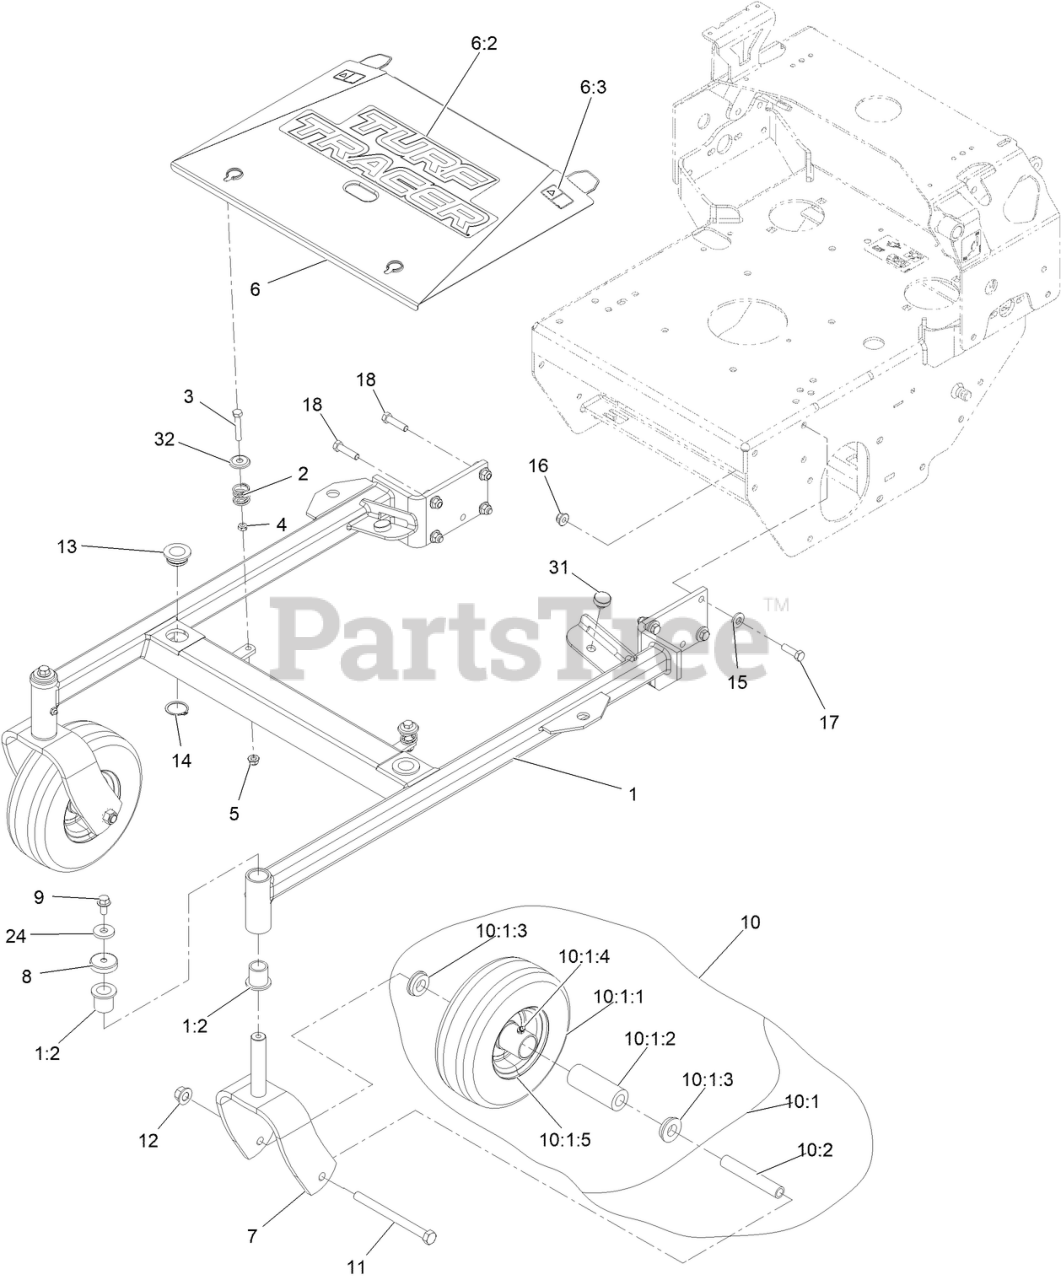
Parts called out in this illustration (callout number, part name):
1	ASM-36" Tts Front Frame
1:2	BEARING-FLANGED
3	SCREW-HH
4	NUT-JAM
5	NUT-HF, NI
6	ASM-36" Tts Center Shield
6:2	DECAL-TURF TRACER
6:3	DECAL-WARNING
7	FORK, CASTER
8	CAP, DUST
9	SCREW-HHF
10	KIT, SP CASTER WHEEL REPLACEMENT
10:1	Wheel And Tire ASM
10:1:1	Tire
10:1:2	BEARING
10:1:3	BUSHING
10:1:4	FITTING-GREASE
10:1:5	Wheel
11	SCREW-HH
12	Nut-Lock 1/2-13
13	BUSHING-DECK
14	RING-RETAINING
15	WASHER-BELLEVILLE
16	NUT-HF, NI
17	SCREW-HH
18	SCREW-HH
31	BUMPER-RUBBER
32	Washer-Cup
